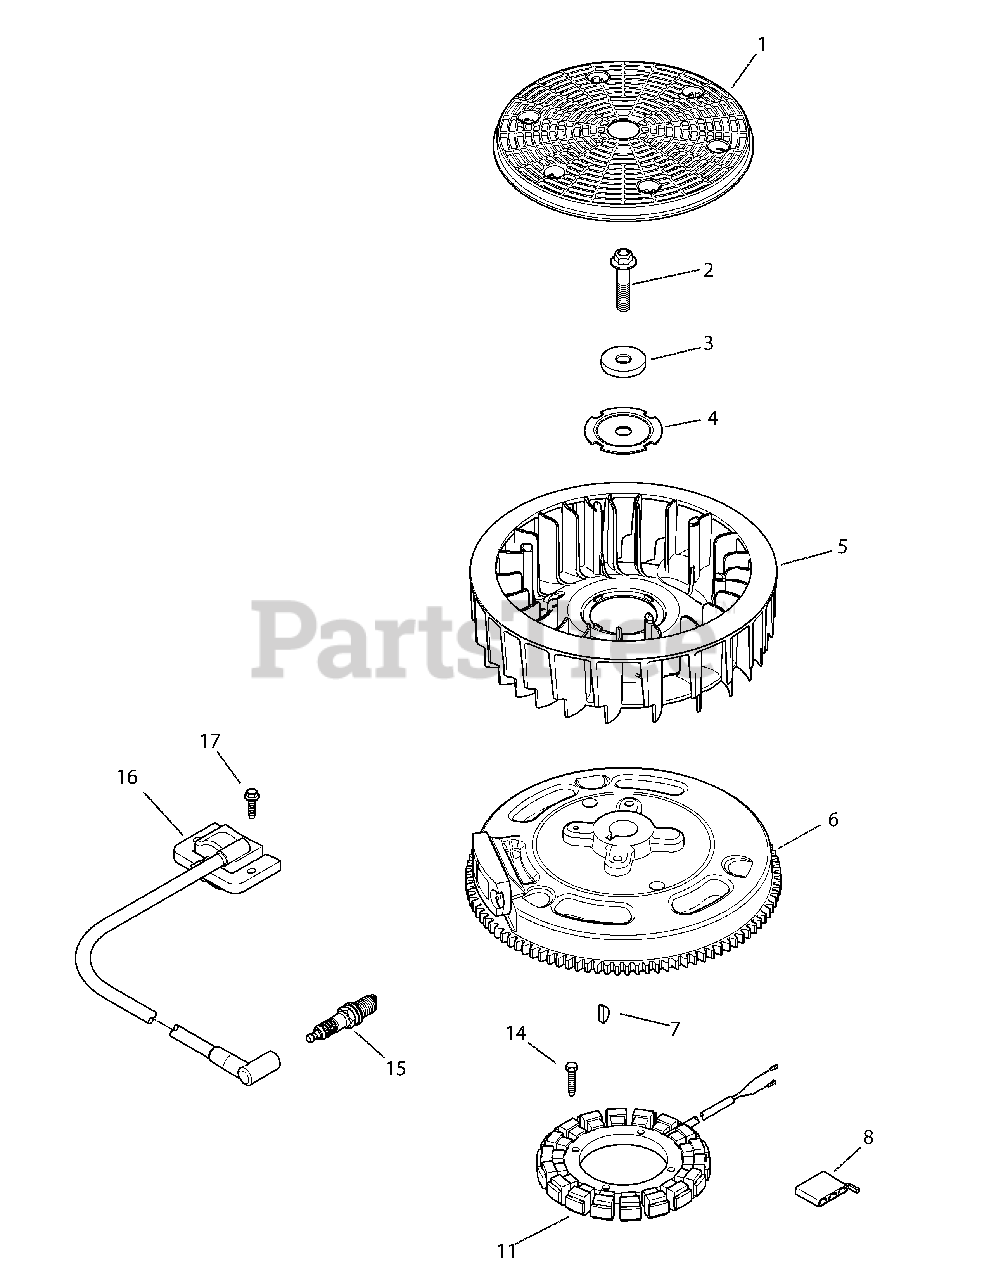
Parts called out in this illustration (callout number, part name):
2	Flg. Screw, M 10 X 1.5 X 45
3	Flat Washer, 13/32
4	Fan Mounting Plate
5	15 Amp Stator Kit (Inc. KH-25-452-01-S)
6	Flywheel Assembly
7	Key, 3/16 X 5/8
11	15 Amp Stator Kit
14	Thd. Frm. Screw, M5 X 0.8 X 25
15	Spark Plug
16	Module Ignition Kit
17	Flg. Thd. Frm. Screw, M5 X .8 X 20
